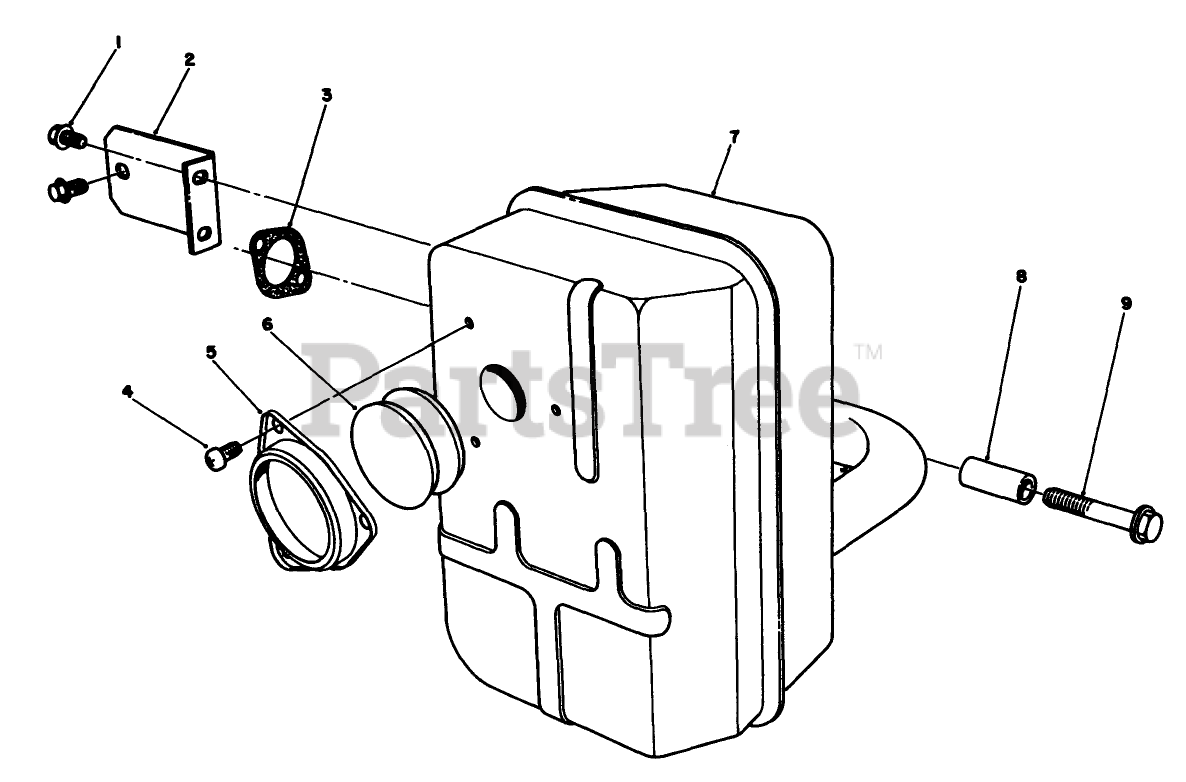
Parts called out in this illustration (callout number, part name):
1	Bolt-Flanged (8X12)
6	Arrester-Spark
7	Muffler Assembly (Incl. Ref.# 4,5 6)
9	Bolt-Flanged (8X45)
